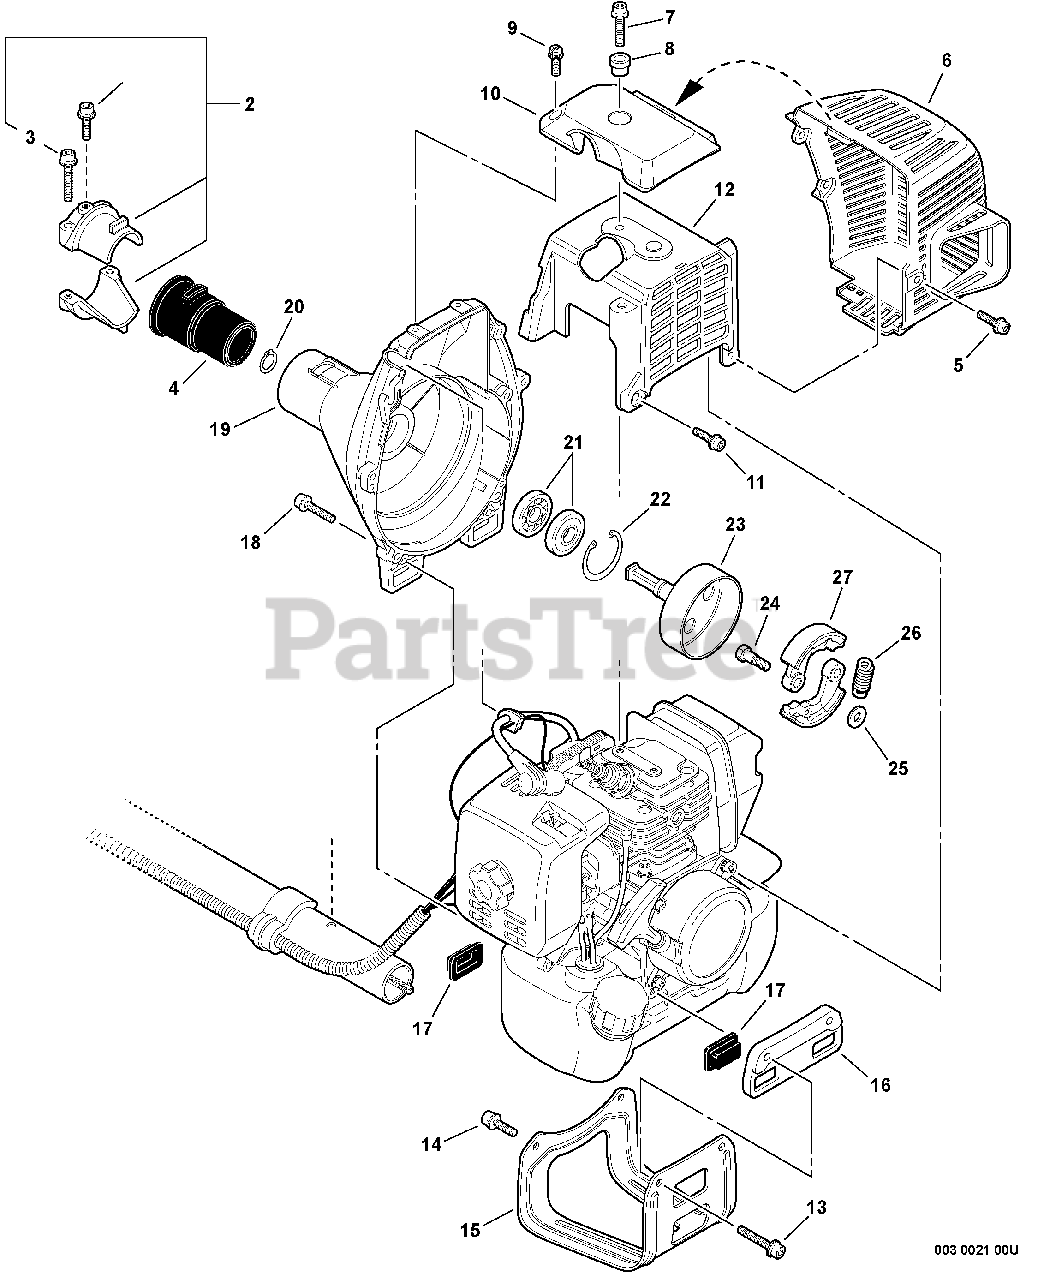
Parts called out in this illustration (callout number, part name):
1	SCREW - 5X12
2	HOLDER KIT
3	SCREW - 5X25
5	SCREW - 5X14
6	COVER, EXHAUST
7	SCREW - 5X20
8	COLLAR - 5
9	SCREW - 4X14
10	GUARD - TOP
11	SCREW - 5X12
12	COVER, ENGINE - GRAY
13	SCREW - 5X20
14	SCREW - 5X12
15	GUARD, FUEL TANK
16	BRACKET, FUEL TANK
17	CUSHION, FUEL TANK
18	SCREW - 5X20
19	CASE, FAN
20	RING, RETAINING - 12
21	BEARING, BALL - 6001
22	RING, RETAINING - 28
23	DRUM, CLUTCH
24	BOLT, CLUTCH
25	WASHER - 6
26	SPRING, CLUTCH
27	SHOE, CLUTCH
